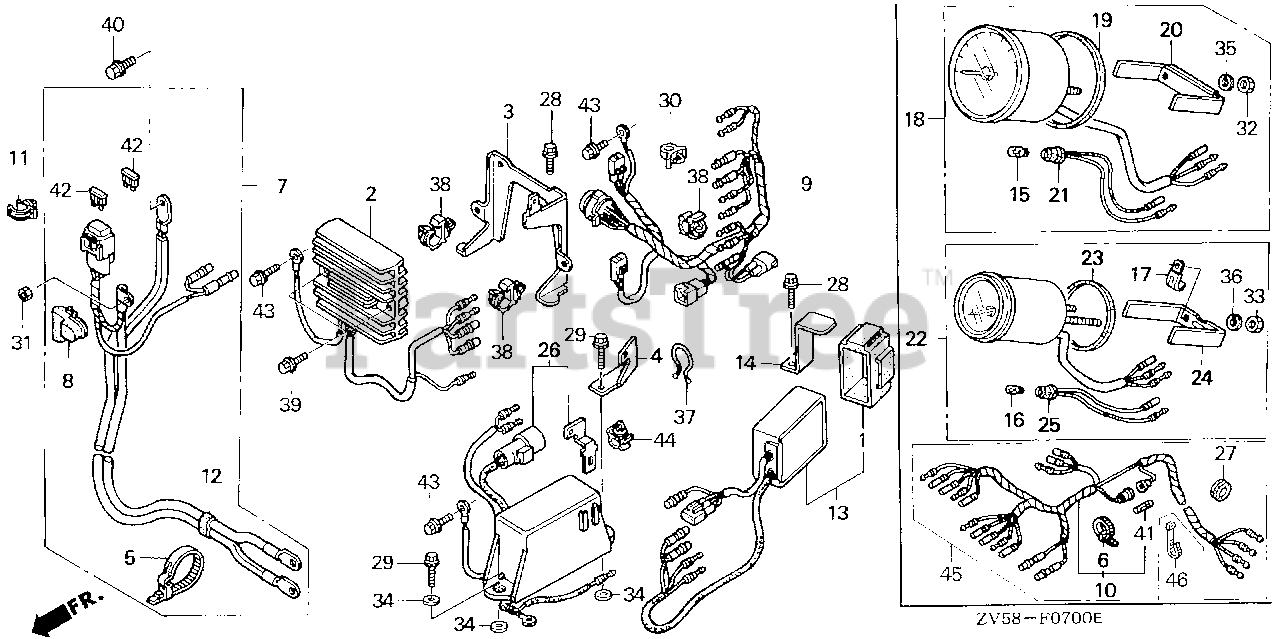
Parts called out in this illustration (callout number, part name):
2	RECTIFIER ASSY., REGULATOR (12A)
3	BRACKET, REGULATOR
4	BRACKET, HARNESS CLIP
5	BAND, WIRE
6	BAND B1, CABLE Use up to Frame SN 1001879.
7	CABLE ASSY., STARTER
8	COVER, TERMINAL
9	CABLE ASSY., REMOTE CONTROL (NOT AVAILABLE)
10	HARNESS ASSY., METER (A)
11	CLAMP, WIRE
12	CLAMP, IGNITION WIRE
15	BULB, WEDGE BASE (T10) (12V 1.7W) (STANLEY)
18	TACHOMETER ASSY. Use from Frame SN 1003229.
20	BRACKET (TO 1015209) (FROM 1015210)
21	SOCKET (TO 1015209) (FROM 1015210)
26	RELAY ASSY., POWER TILT
28	BOLT, FLANGE (6X12) (CT200)
29	BOLT, FLANGE (6X18) (CT200)
30	HOLDER, ROD (6MM)
31	NUT, HEX. (6MM)
32	NUT, HEX. (5MM)
34	WASHER, PLAIN (6MM)
35	WASHER, SPRING (5MM)
37	CLIP, PURSE LOCK
38	CLIP, WIRE HARNESS
39	BOLT, FLANGE (6X20)
40	BOLT, FLANGE (8X12)
41	FUSE A (10A)
42	FUSE, BLADE (15A)
43	BOLT, FLANGE (6X12) (CT200)
44	CLIP, CORD
